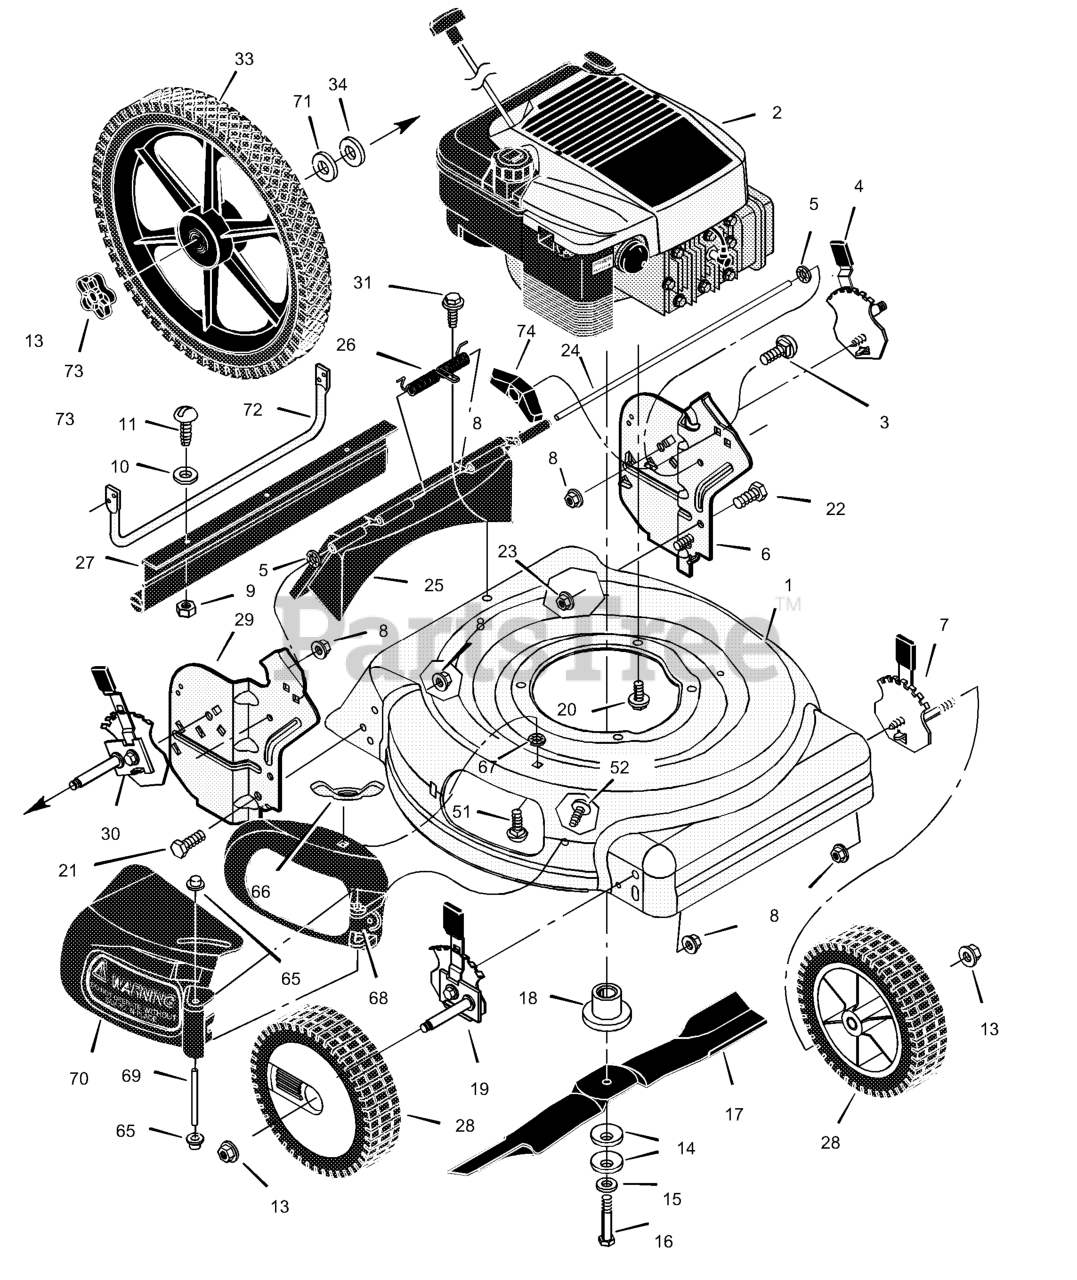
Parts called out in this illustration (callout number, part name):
2	Engine *
3	Bolt, Carriage
4	Adjuster, Left Rear Height
5	Push On Cap
6	Bracket, Left Handle
7	Adjuster, Left Front Height
8	Nut, Flange
9	Nut, Hex
12	Hub Cap
13	Nut, Flange
14	Washer, Belleville
18	Adapter, Blade
19	Adjuster, Right Front Height
20	Bolt, Engine
21	Bolt
22	Bolt
22	Washer
23	Nut, Flange
24	Rod, Pivot
25	Door, Rear
26	Spring
27	Guard, Rear
28	Wheel & Tire
29	Bracket, Right Handle
30	Adjuster, Right Rear Height
33	Wheel, Rear
51	Bolt, Carriage
65	Push On Cap
66	Wingnut
68	Bezel
69	Pin, Pivot
70	Deflector, Chute
